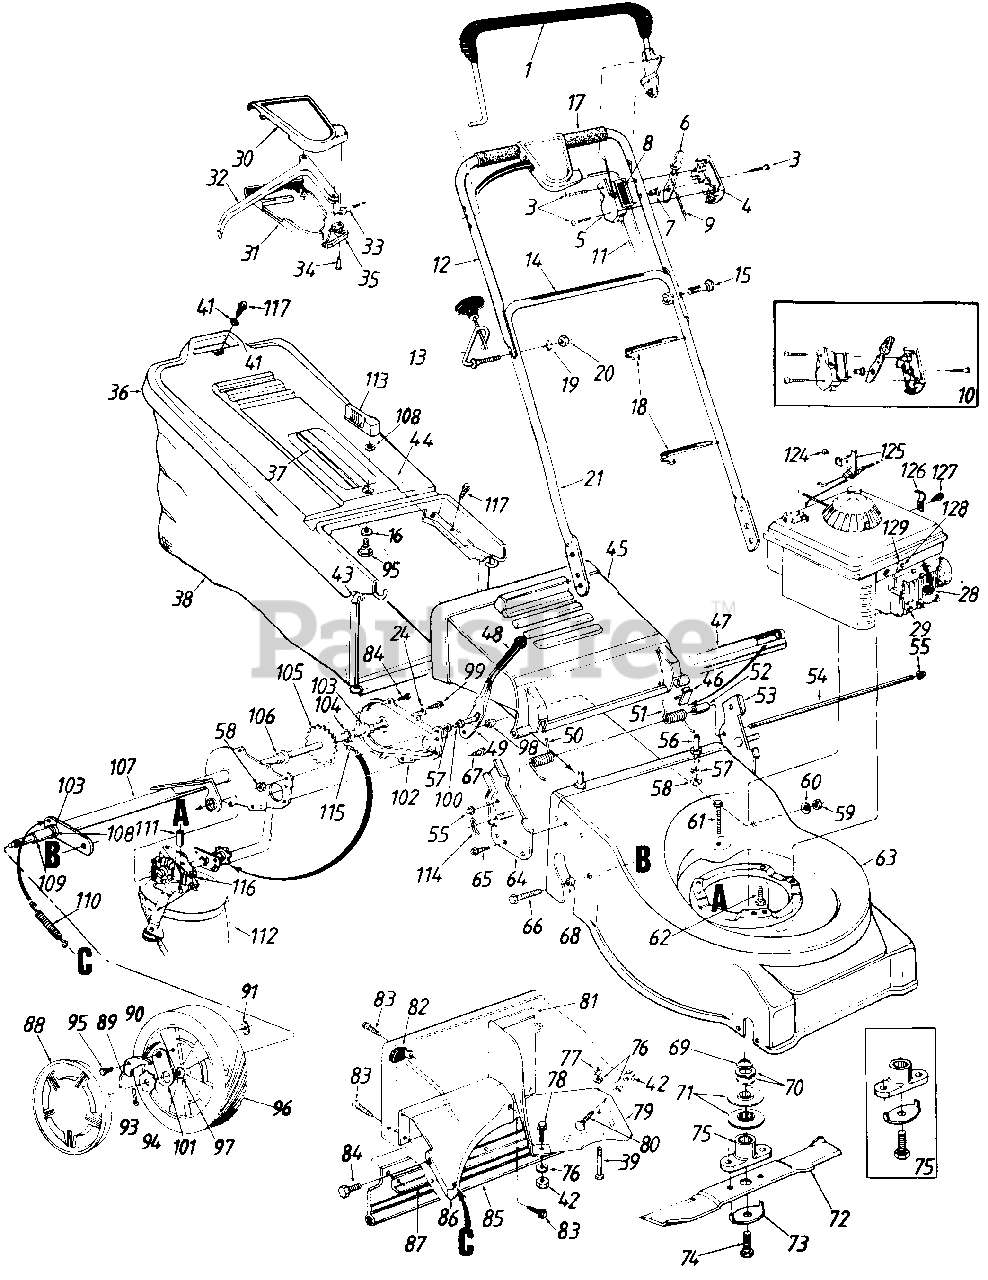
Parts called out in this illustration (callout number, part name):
1	Control Handle Ass'y.
3	Truss Mach. B-Tap Scr. #12 x 1.5" Lg.
4	Control Panel Half
5	Clutch Panel Half
6	Throttle Control Lever
7	Control Disc Pin
8	Control Label-Throttle
9	Throttle Wire-58" Lg.
10	Control Housing Comp.
11	Control Cable-43" Lg.
12	Upper Handle
13	Rope Guide Bolt
14	Instruction Label-Handle
15	Curved Carriage Bolt 5/16-18 x 1.38" Lg.
16	Bowed Washer
17	Foam Grip
18	Cable Tie
19	L-Wash. 5/16" I.D.
20	Hex Nut 5/16-18 Thd.
21	Lower Handle
24	Bell-Wash. .265" I.D. x .75"
28	Spark Plug Boot
29	Engine
30	Control Cover Half-Upper
31	Control Cover Half-Lower
32	Control Lever
33	Drive Cable-53" Lg.
34	Flat C-Sunk Hd. Tap Scr. #10 x .75" Lg.
35	Cable Mtg. Cap
36	Hardtop Bag Cover
37	Hardtop Handle
38	Grass Bag
39	Truss Mach. Scr. 1/4-20 X 1.0" Lg.
41	Fl-Wash. .281" I.D. x .62"
42	Hex Nut 1/4-20 Thd.
43	Front Catcher Frame
44	Rear Catcher Frame
45	Chute Deflector
46	Deflector Plug
47	Seal-Extrusion
49	Spring Lever
50	Torsion Spring-R.H.
51	Torsion Spring-L.H.
52	Spacer.255" I.D.
53	Handle Brkt. Ass'y.-L.H.
54	Hinge Pin 17.75" Lg.
55	Cap Speed Nut
56	Shld. Pin 3/8-24 x 1.43" Lg.
57	L-Wash. 318" I.D.
58	Hex Jam Nut 3/8-24 Thd.
59	Hex L-Nut 3/8-24 Thd.
60	Bell-Wash. .38" I.D. x .88"
61	Hex Wash. Hd. Tap Scr. 1/4-20 X 1.5" Lg.
62	Hex L-Wash. Hd. Scr. 3/8-16x1" Lg.
63	483 21" Deck Ass'y.
64	Handle Brkt. Ass'y.-R.H.
65	Hex L-Wash. Hd. AB-Tap Scr. 1/4 x.62" Lg.
66	Hex Wash. Hd. Tap Scr. 3/8-16 x .75" Lg.
67	Hex Wash. Hd. Tap Scr. 1/4-20 x .5" Lg.
68	Spacer .383" I.D.
69	Serrated Washer 1.0" I.D.
70	Wave Washer 1.005" I.D.
71	Serrated Pulley Half
72	21" Blade
73	Blade Bell-Wash. .44" I.D.
74	Hex Bolt 7/16-20 x 1.5" Lg. (Gr. 5)
75	Blade Adapter Kit
76	L-Wash. 1/4" I.D.
77	Hex Jam Nut 1/4-20 Thd.
78	Hex Bolt 1/4-20 x .85" Lg.
79	Rear Belt Baffle
80	Carr. Bolt 1/4-20 x .50" Lg.
83	Torx Mach. AB-Tap Scr. 1/4 x .62" Lg.
84	Hex B-Tap Scr. 1/4 x .38" Lg.
85	Rear Flap
89	Plastic Spring
90	Pawl .345" I.D.
91	Weld Nut 1/4-20 Thd.
93	Cotter Pin 1/8" Dia.
94	Ratchet Wheel 1.62" O.D.
95	Shld. Bolt .342" Dia. x .268"
96	Wheel Ass'y. Comp.-Rear
97	Sleeve Bearing 1/2" I.D.
98	Shld. Spacer .50" Dia.
99	Hex Bolt 1/4-20 x .62" Lg. (Gr. 5)
100	Shld. Pin 3/8-24 x 1.43" Lg.
101	Pawl Plate
104	Fl-Wash. .531" I.D. x .93"
105	Rear Axle Ass'y.
106	Hex Flange Bearing
109	Spacer .513" I.D.
110	Extension Spring 3.8" Lg.
111	Spacer .325" I.D.
112	V-Belt
113	Grass Catcher Locking Knob
114	Internal Cotter Pin 5/16" Dia.
115	#48 Chain .50" Pitch x 30 Links
116	Transmission Comp.
117	Hex L-Wash. H.D. AB-Tap Scr. 1/4 X .62" Lg.
124	Pop Rivet .156" Dia.
125	Cable Brkt.
126	Cable Clamp
127	Hex B-Tap Scr. #10 x .38" Lg.
128	Hex B-Tap Scr. #10 x .62" Lg.
